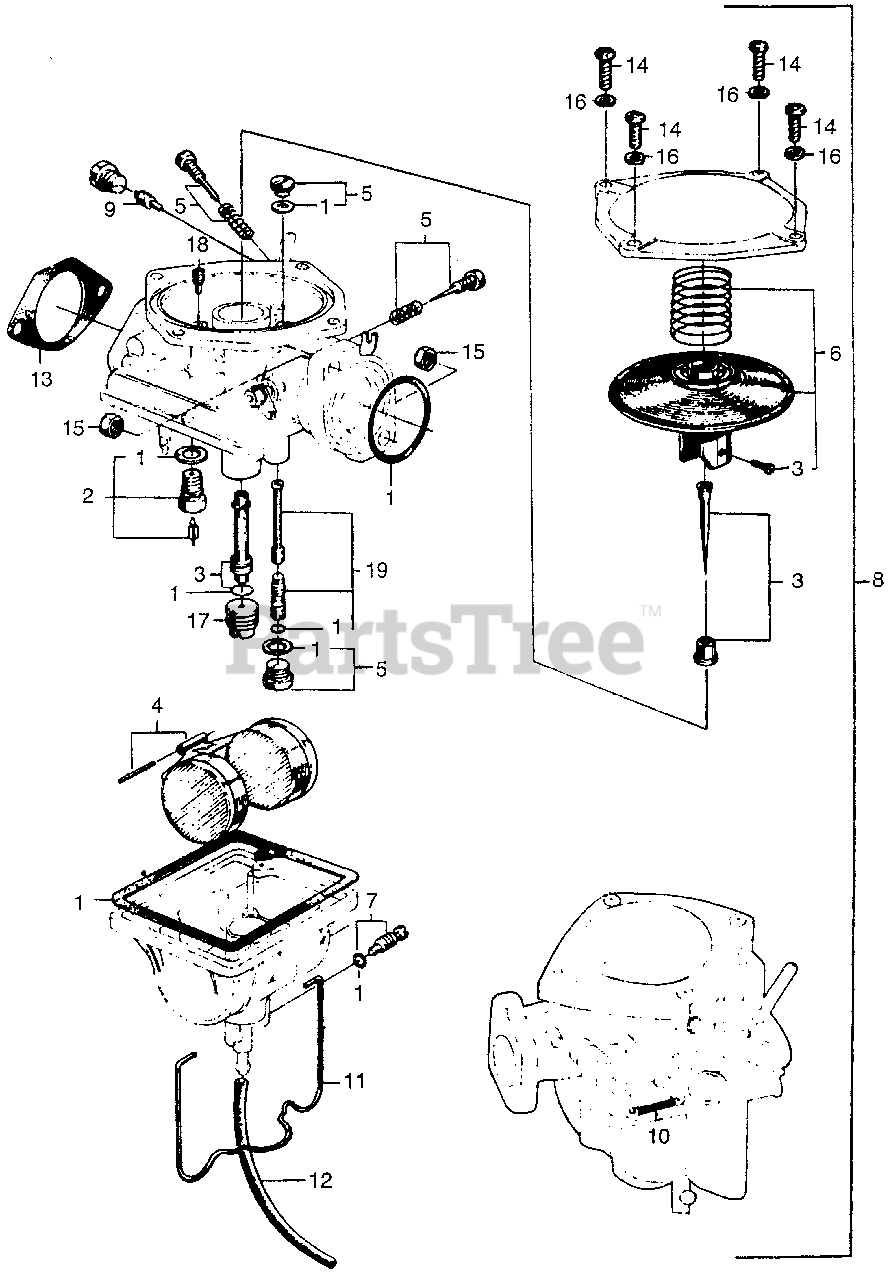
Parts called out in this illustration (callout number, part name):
1	GASKET SET
2	VALVE SET, FLOAT (NOT AVAILABLE)
3	NEEDLE SET, JET
4	FLOAT SET (NOT AVAILABLE)
5	SCREW SET A (NOT AVAILABLE)
6	VALVE SET, THROTTLE (NOT AVAILABLE)
7	SCREW SET, DRAIN (NOT AVAILABLE)
8	CARBURETOR ASSY. (NOT AVAILABLE)
9	SCREW, PILOT STOP
10	SPRING, PISTON
11	CLIP, FLOAT CHAMBER
12	PIPE, OVERFLOW
12	BULK HOSE, FUEL (3.5X3000) (3.5X150)
13	GASKET, AIR CLEANER (NOT AVAILABLE)
14	SCREW, PAN (5X12)
15	NUT, HEX. (6MM)
16	WASHER, SPRING (5MM)
17	JET, MAIN (#68) (NOT AVAILABLE)
17	JET, MAIN (#70) (NOT AVAILABLE)
17	JET, MAIN (#72) (NOT AVAILABLE)
17	JET, MAIN (#75)
17	JET, MAIN (#78) (NOT AVAILABLE)
17	JET, MAIN (#80)
17	JET, MAIN (#82) (NOT AVAILABLE)
17	JET, MAIN (#85)
19	JET SET, PILOT (#45) (NOT AVAILABLE)
